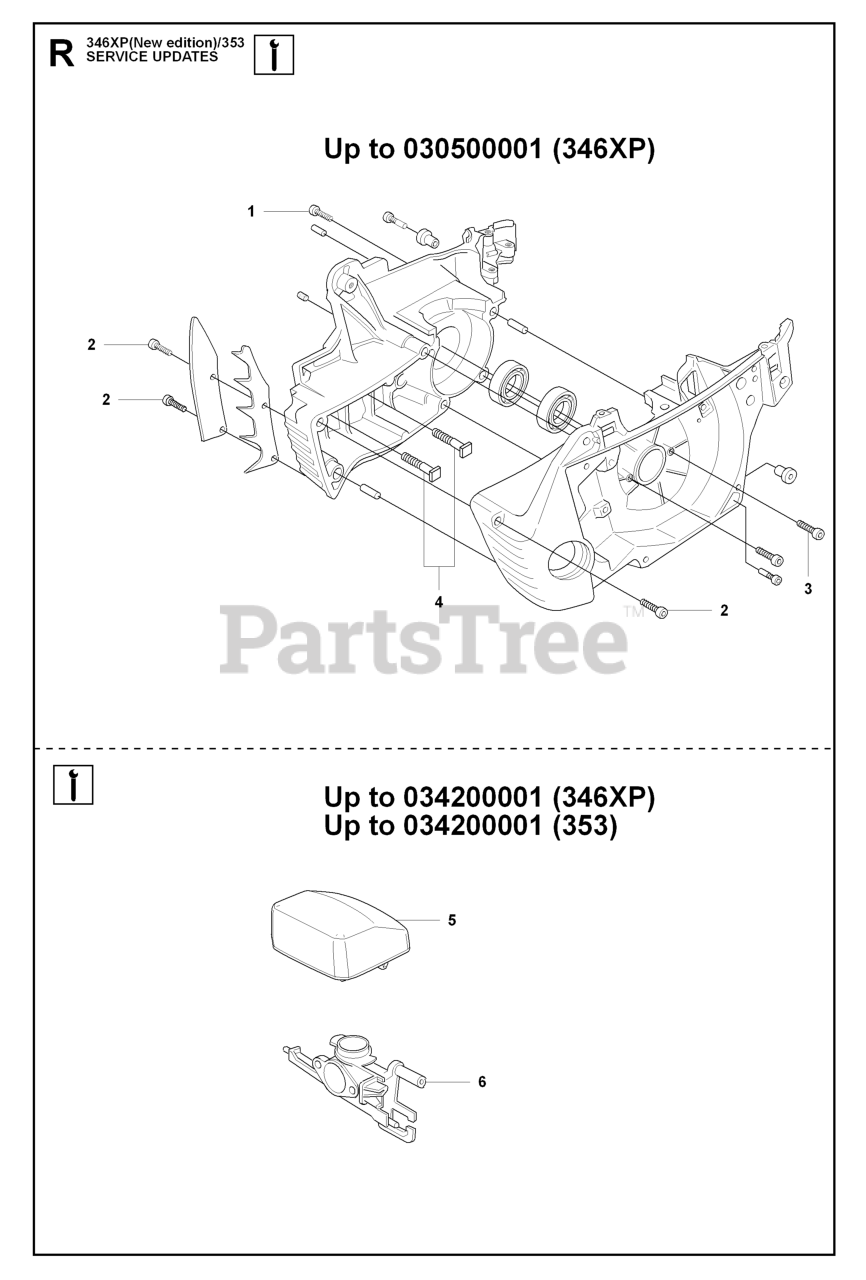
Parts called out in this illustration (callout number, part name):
1	SCREW
2	SCREW
3	SCREW
5	AIR FILTER - FELT
5	AIR FILTER - NYLON (Y)
5	AIR FILTER - NYLON (B)
